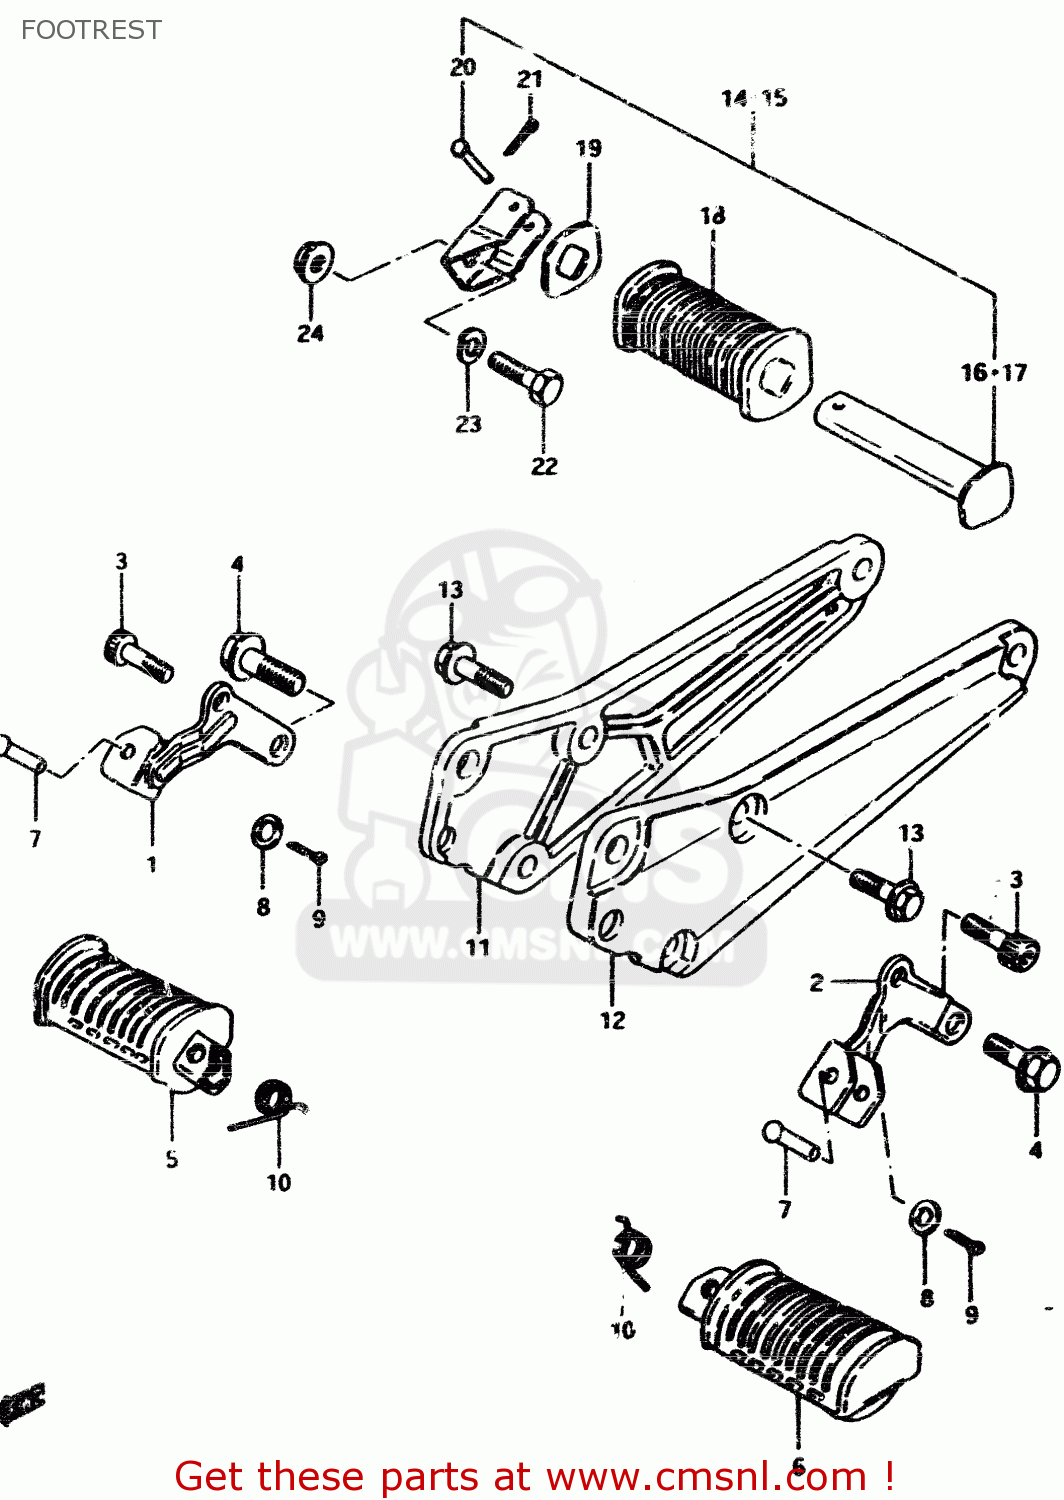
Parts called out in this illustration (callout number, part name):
1	BAR,FRONT FOOTREST,RIGHT
2	BAR,FRONT FOOTREST,LEFT
3	BOLT
4	BOLT
5	RUBBER,PILLION FOOTREST,R
6	RUBBER,PILLION FOOTREST,L
7	PIN
8	WASHER
9	PIN 20X20
10	SPRING
11	BRACKET,MUFFLER,RIGHT
12	BRACKET,MUFFLER,LEFT
13	BOLT
14	FOOTREST ASSY,PILLION,R
15	FOOTREST ASSY,PILLION,L
16	BAR,REAR FOOTREST,RIGHT
17	BAR,REAR FOOTREST,LEFT
18	RUBBER,PILLION FOOTREST
19	WASHER,FOOTREST RUBBER
20	PIN
21	PIN 20X20
22	BOLT,M10X1.25X
23	LOCK WASHER
24	NUT
